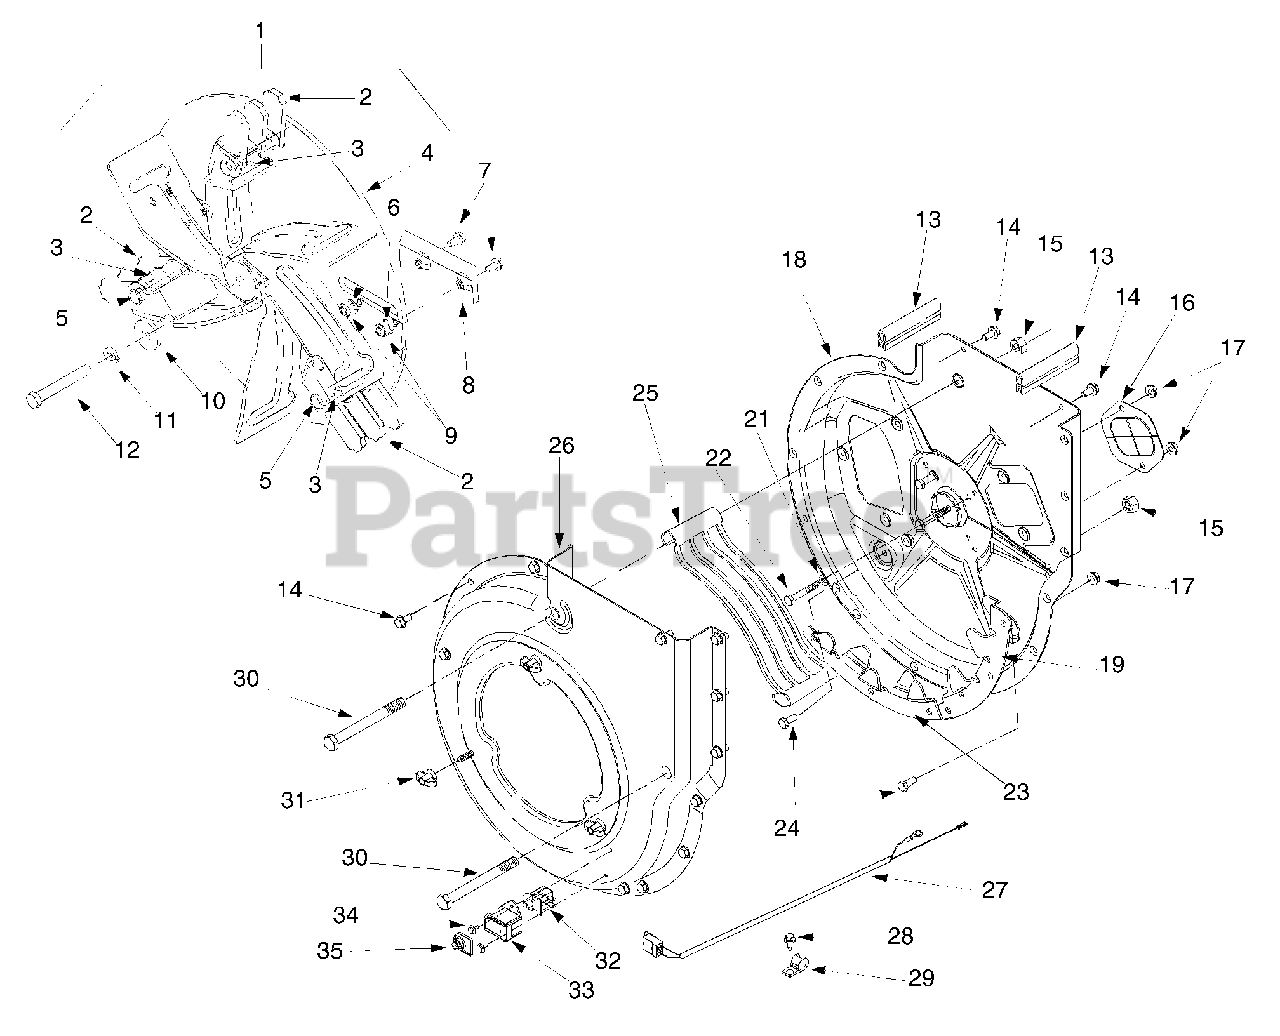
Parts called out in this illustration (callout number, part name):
1	Impeller Ass'y Complete
2	Flail Blade
3	Spiral Pin
4	Impeller Assembly
5	Clevis Pin
6	Lock Washer 5/16
7	Cap Screw 5/16-24 x 1.0
8	Chipper Blade
9	Hex Lock Nut 5/16-24
10	Flat Washer .406 x 1-1/4
11	Lock Washer 3/8
12	Hex Cap Screw 3/8-24 x 2.75
13	Rubber Seal
14	Hex Washer Screw 5/16-18
15	Hex Lock Nut 1/2-13
17	Hex Flange Lock Nut 5/16-18
21	Lock Washer 5/16
22	Hex Cap Screw 5/16-18 x 2
24	Hex Cap Screw 5/16-18 x .75
25	Discharge Screen
27	Wire Harness
28	Hex Washer Screw 1/4-14
30	Hex Cap Screw 1/2-13 x 5.0
31	Knob 5/16-18
32	Switch
33	Safety Switch Mounting Cover
34	Hex Washer Screw
35	Switch Cover
